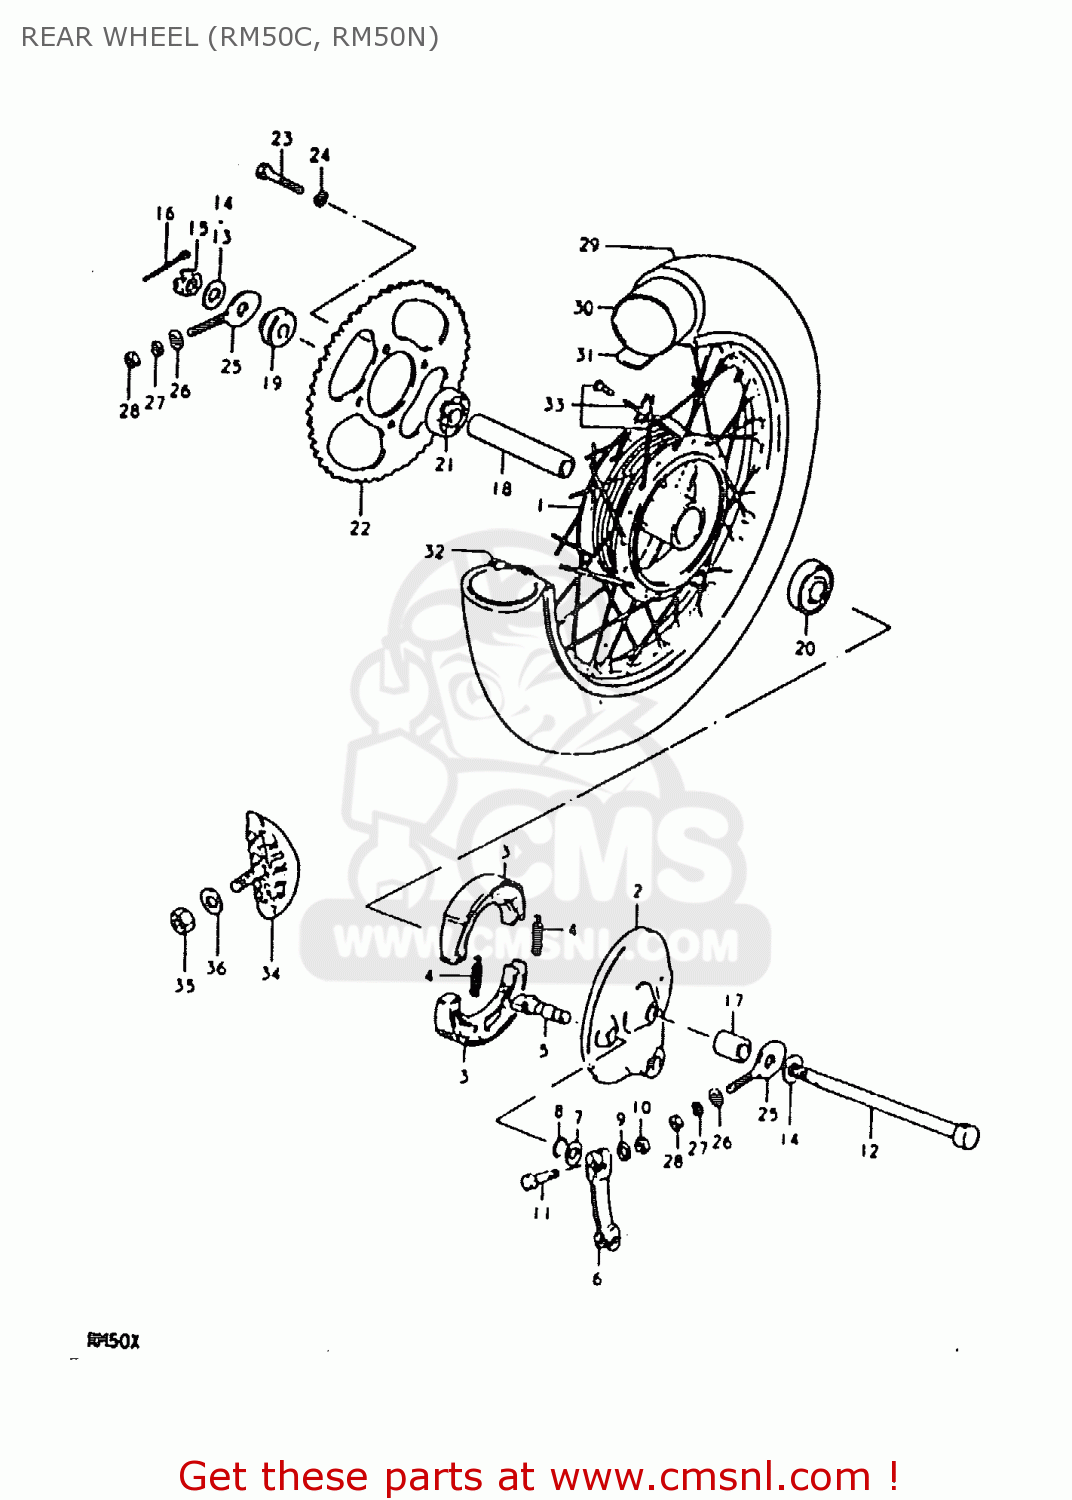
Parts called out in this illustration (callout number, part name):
1	DRUM,REAR HUB
2	PANEL,REAR BRAKE ANCHOR
3	SHOE,BRAKE
4	SPRING(L:34)
5	CAM,FRONT BRAKE
6	LEVER,REAR BRAKE CAM
7	WASHER (14.5X22X1.6)
8	O-RING (D:2.4 ID:13.8)
9	WASHER
10	NUT
11	BOLT(6X33)
12	AXLE,REAR
13	WASHER
14	WASHER
15	NUT 12MM
16	COTTER PIN
17	SPACER (12.1X22X27)
18	SPACER(12.6X19X91)
19	SPACER,RR AXLE,L
20	BEARING, RH
21	BEARING, REAR HUB LH
22	SPROCKET,RR(NT:42)
23	BOLT
24	LOCK WASHER
25	ADJUSTER,CHAIN,R
26	WASHER
27	LOCK WASHER
28	NUT
29	TIRE
30	TUBE,INNER
31	PROTECTOR,INNER TUBE
32	RIM,REAR WHEEL
33	SPOKE SET,REAR WHEEL
34	STOPPER,BEAD
35	NUT
36	WASHER
